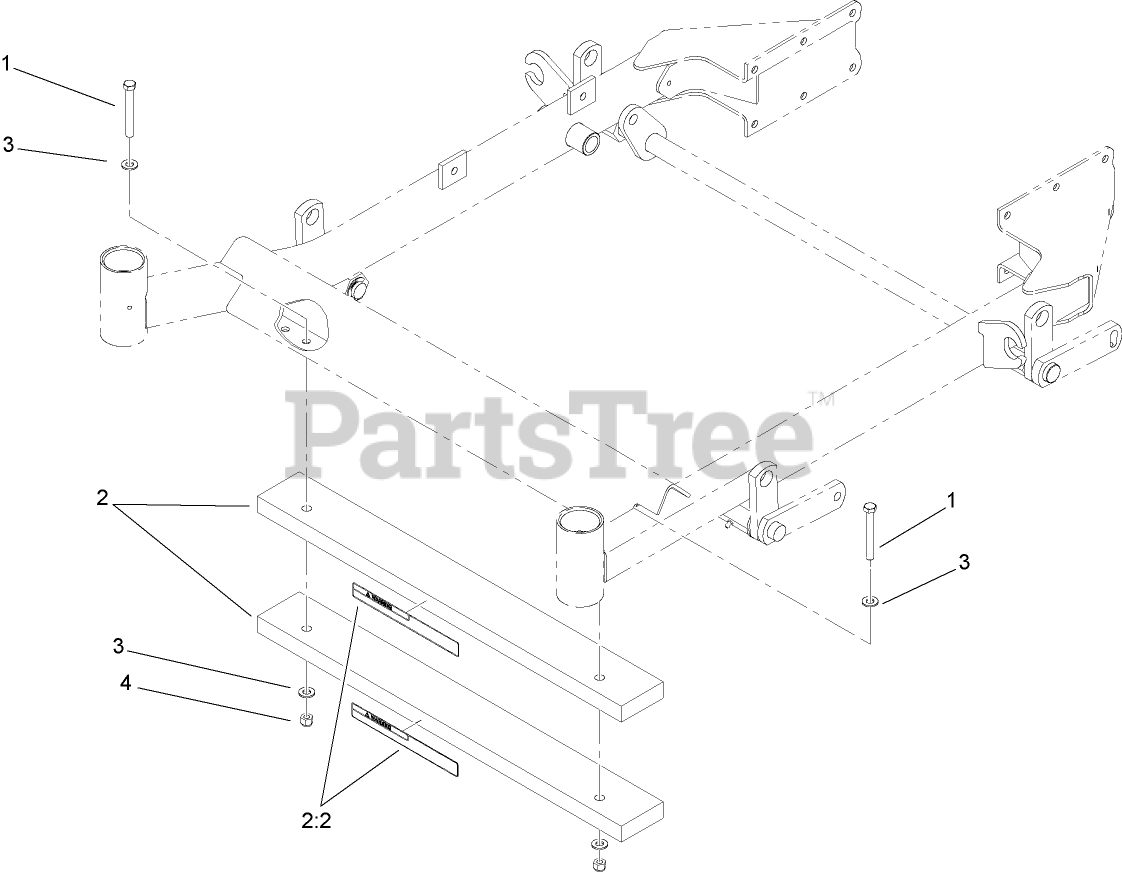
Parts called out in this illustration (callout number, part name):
1	SCREW-HH
2	WEIGHT
2:2	DECAL-WARNING, COUNTER WEIGHT
3	WASHER-FLAT
4	NUT-LOCK, NI
